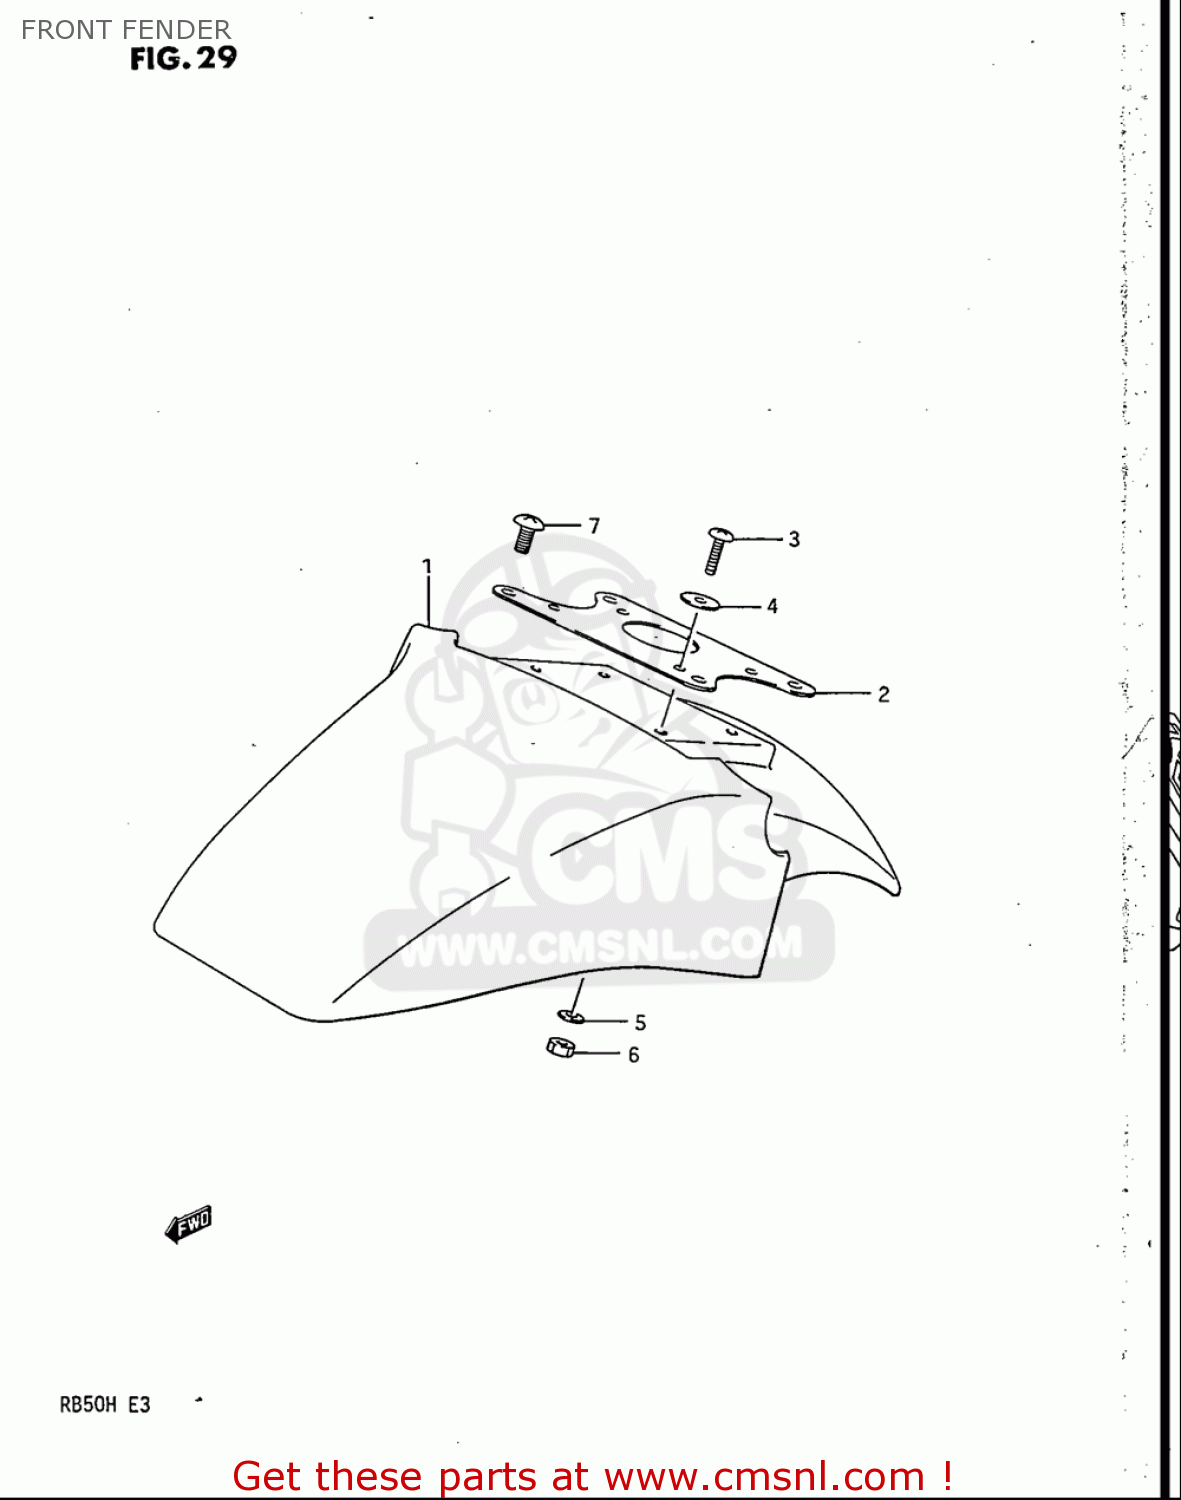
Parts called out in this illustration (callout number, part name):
1	FENDER,FR
2	BRACE,FR FENDER
3	SCREW
4	WASHER(5.5X18X1)
5	LOCK,WASHER
6	NUT
7	SCREW 6X12
